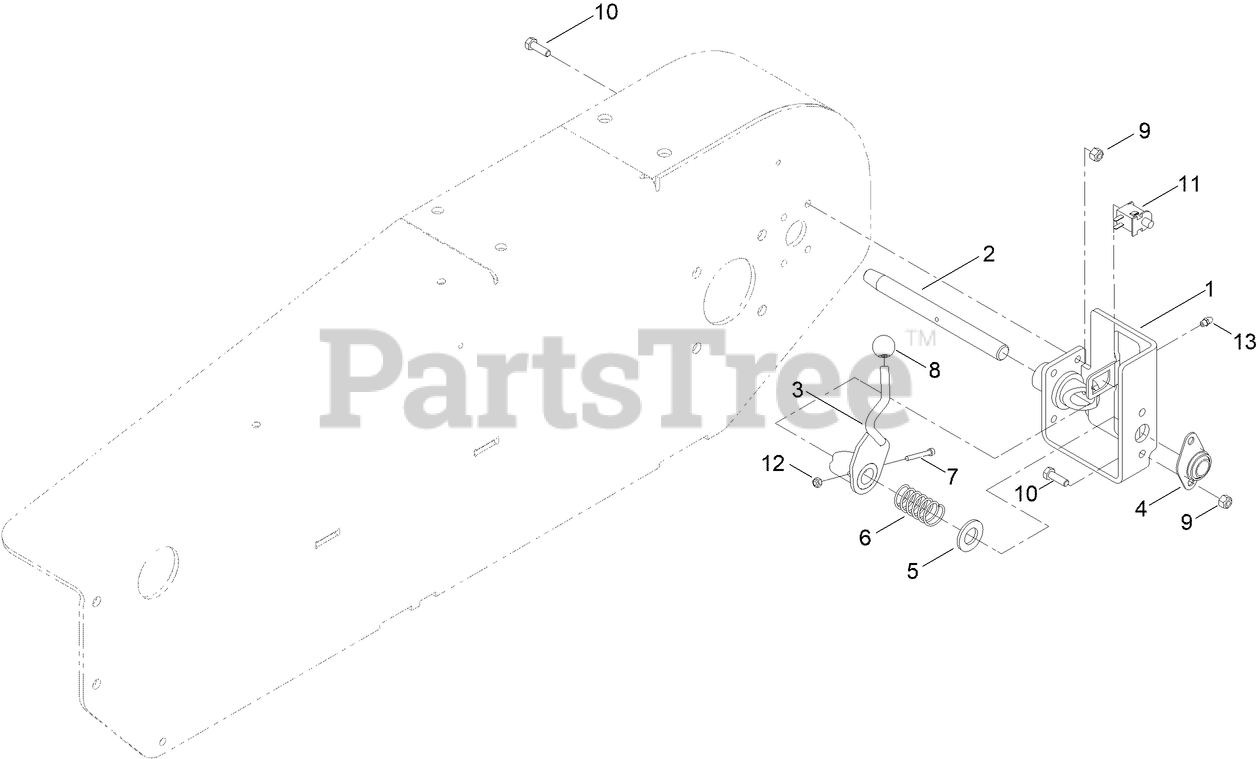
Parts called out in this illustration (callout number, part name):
1	BRAKE BRACKET ASM
2	SHAFT-BRAKE
3	BRAKE HANDLE ASM
4	BEARING
5	WASHER-FLAT
6	SPRING-COMPRESSION
7	SCREW-HSH
9	NUT-LOCK, NI
10	SCREW-HH
11	SWITCH
12	NUT-LOCK, NI
13	FITTING-GREASE
